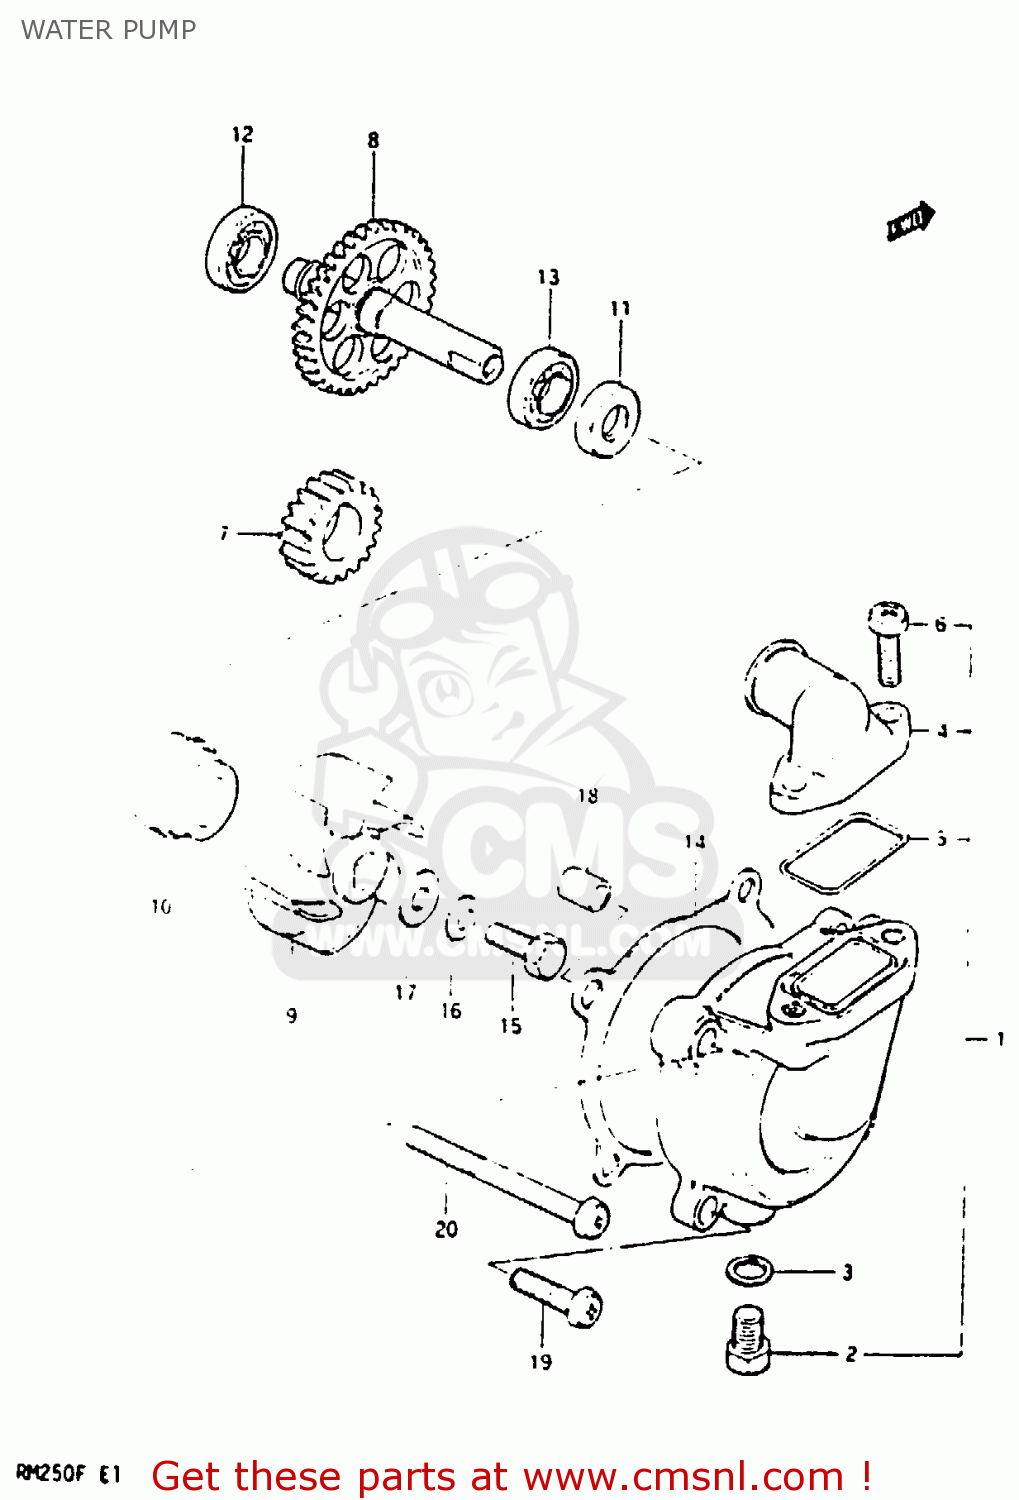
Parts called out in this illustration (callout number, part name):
1	CASE,WATER PUMP
2	BOLT,DRAIN
3	GASKET,DRAIN (NAS)
4	CONNECTOR
5	O RING,WATER PUMP CONNECTOR
6	SCREW
7	GEAR,WATER PUMP DRIVE
8	GEAR,WATER PUMP DRIVEN(NT:36)
9	IMPELLER,WATER PUMP
10	SEAL,WATER PUMP SHAFT
11	SEAL,OIL(10X21X5)
12	BEARING(10X22X6)
13	BEARING
14	GASKET,WATER PUMP CASE (MCA)
15	BOLT(6X13)
16	WASHER
17	GASKET (NAS)
18	PIN
19	SCREW
20	SCREW (6*60)
